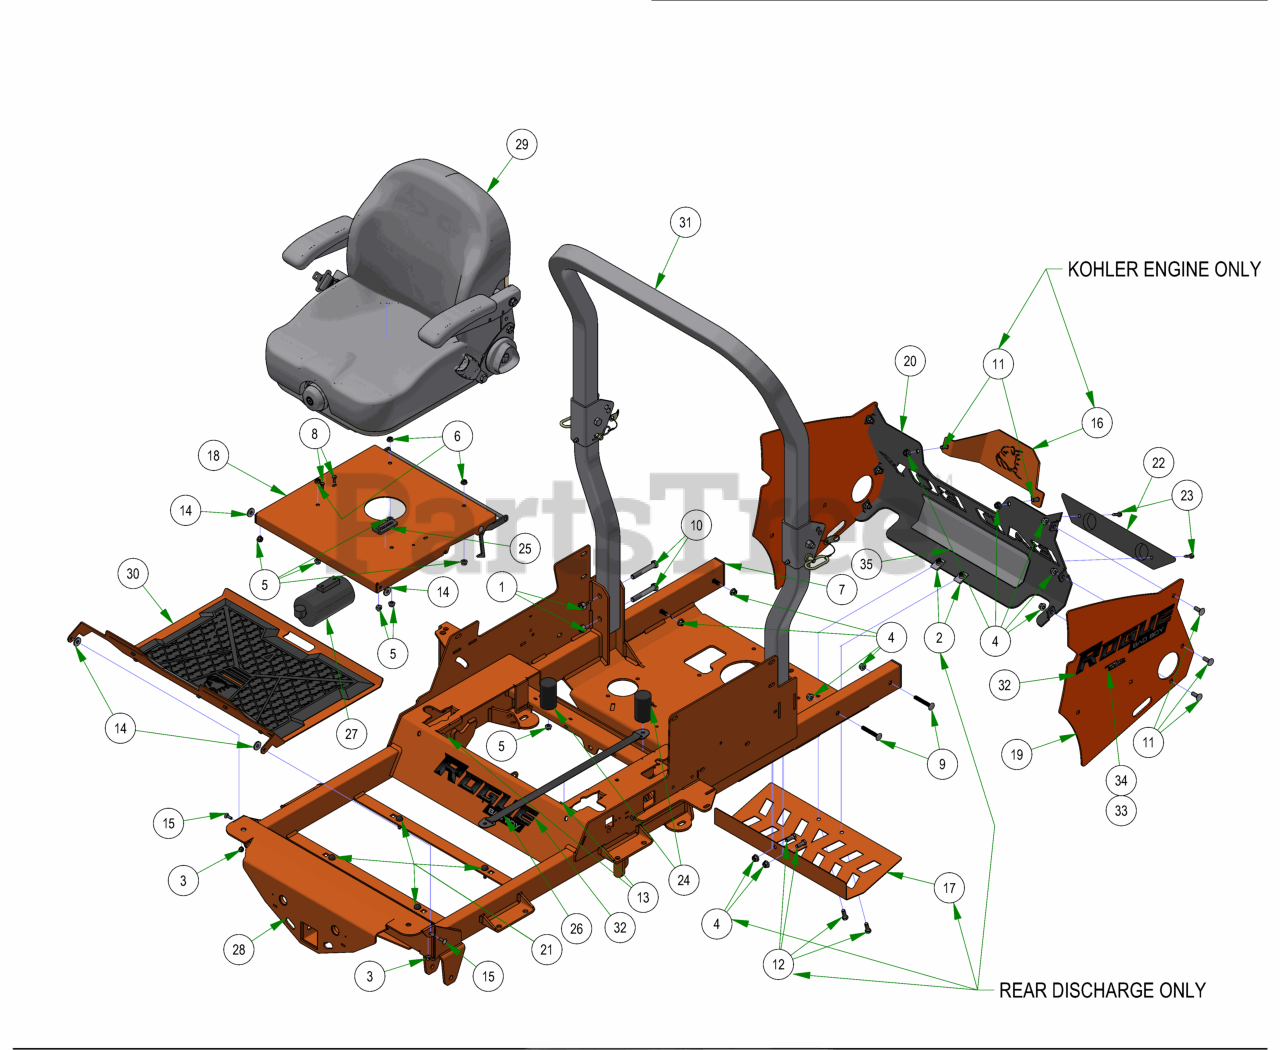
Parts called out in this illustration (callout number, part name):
1	1/2-13 HEX 2-WAY REVERSIBLE CENTER LOCKNUT Grade B ZINC
2	Extruded Nut 3/8"-16 3/4" Hole Center With Patch
3	1/4-20 NYL INSERT FLANGE LOCKNUT ZINC
4	3/8-16 NYLON INSERT FLANGE LOCKNUT (GR.F) ZINC
5	5/16-18 NYLON INSERT FLANGE LOCKNUT ZINC
6	5/16-18 HEX SERRATED FLANGE NUT HARD/ZINC
7	1 1/2 x 3 Frame Plug
8	M6-1.0 X 16MM DIN 933 HEX TAP BOLT (CL 8.8) ZINC
9	3/8" x 2 1/2" Carriage Bolt
10	1/2-13 X 3-1/4 HEX CAP SCREW (GR.5) ZINC
11	3/8-16 X 1 CARRIAGE BOLT (GR.5) ZINC
12	3/8-16 X 1 GR 5 Hex Bolts Zinc
13	5/16-18 X 1 CARRIAGE BOLT (GR.8) ZINC
14	.360 ID X .983 OD X .120 THICK FLAT WASHER NYLON
15	1/4-20 X 3/4 CARRIAGE BOLT (GR.5) ZINC
16	Kohler 980 Engine Shield
17	Muffler Shield - Rear Discharge
18	R-SERIES SEAT PLATE ASSEMBLY
19	2019 Rouge Rear Cover Side Plate
20	2019 Vertical Rear Cover Tailgate - Black
21	2023 Floor Board Rubber Bumper
22	2017 XP Bumper
23	1/4-14 X 1-1/4 HEX WASHER UNSLOT TEK/3 ZINC
24	2019 Bad Boy X Cylindrical Seat Mount
26	Seat Strap with Buckles
27	2019 Outlaw EPA Cannister Assembly
28	2023 Rogue Frame - Painted
29	2025 Seats Inc Suspension
30	2024 R-Series Floorboard Assembly
31	2019 2X2 Folding ROPS
32	Rogue back Plate & Front Decal
33	2022 Powered By Kawasaki Decal
34	2022 Powered By Kohler Decal
35	Heat Shield (Fiberglass Adhesive)
